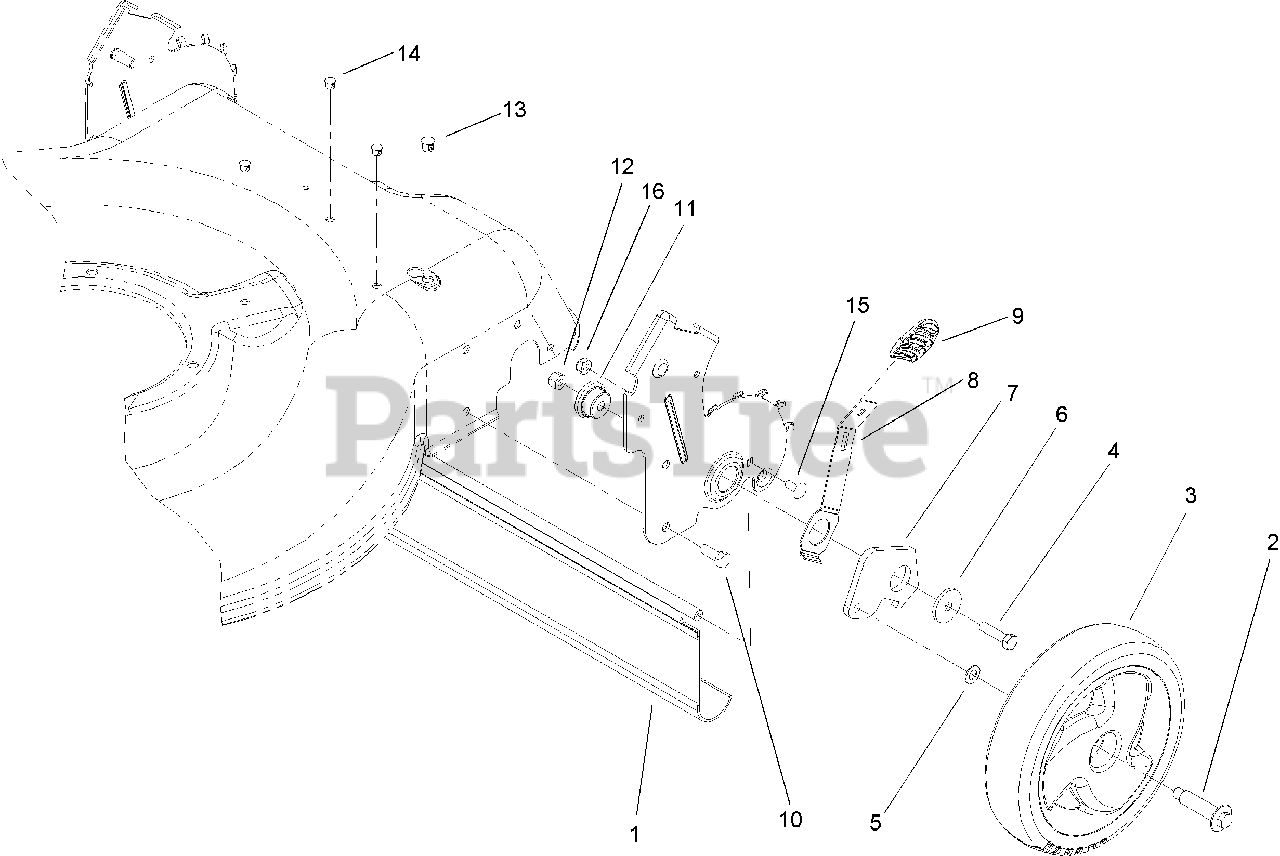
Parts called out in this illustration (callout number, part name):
1	Shield-Trailing
2	BOLT-SHOULDER
3	8IN WHEEL ASM
4	SCREW-HH
6	Washer-Flat
7	Arm-Pivot, Rear
8	Arm-Spring
9	KNOB-LEVER, HOC
10	SCREW-HH
11	Bushing-Mount, HOC
12	NUT-LOCK, NI
13	Plug-Dome
14	Plug-Dome
15	SCREW-CARR
16	NUT-LOCK, NI
